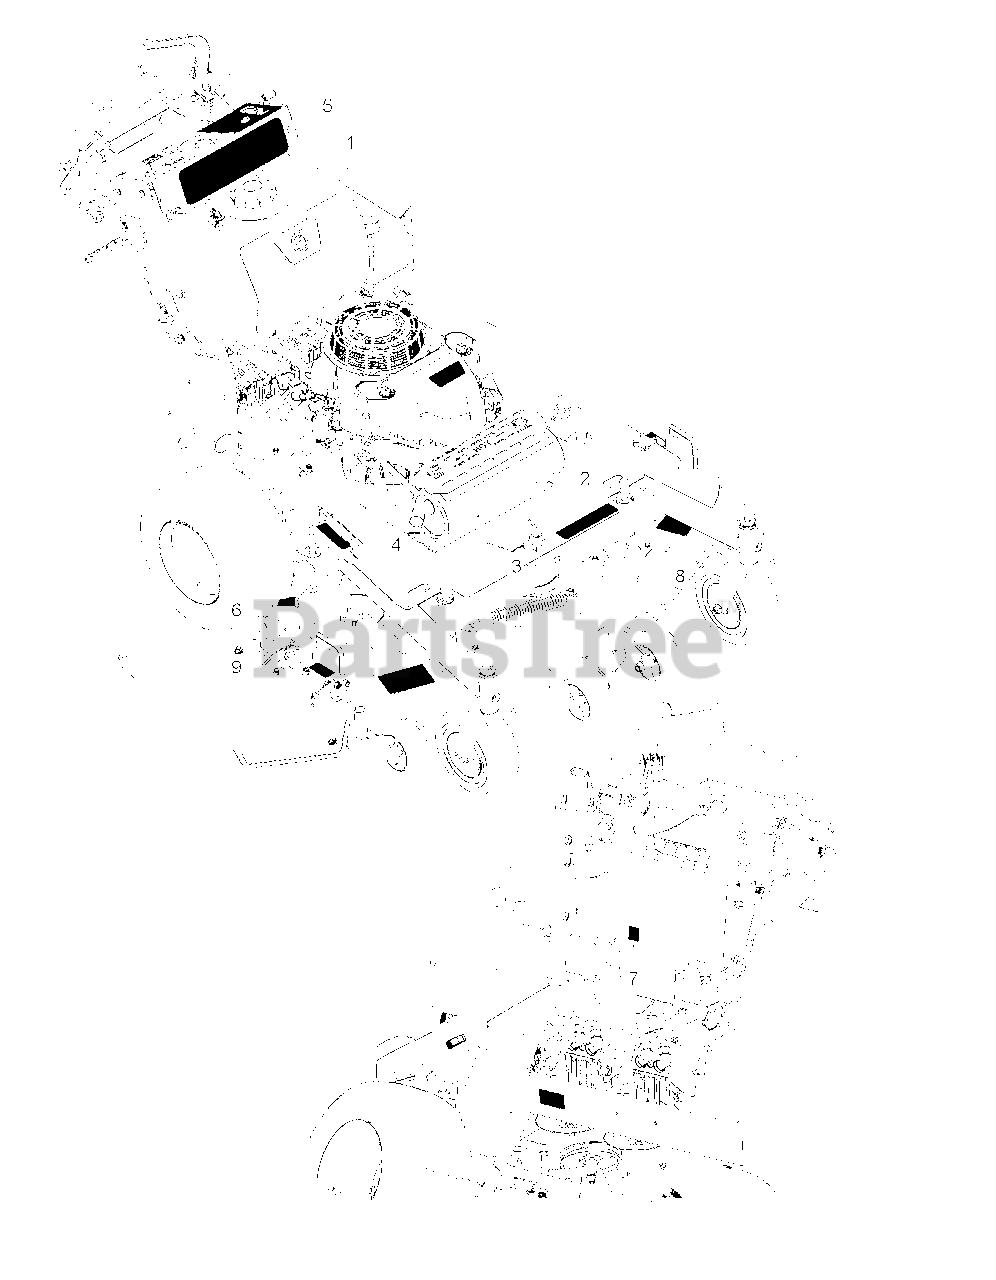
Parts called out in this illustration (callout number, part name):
5	DECAL SOURCED STAND-ON GRAPHIC
6	DECAL DECAL, SAFETY - DECK GUA
7	DECAL HOT SURFACE 7754100
8	DECAL DECAL, SAFETY - MOWER DE
9	DECAL PUMP BELT ROUTING 200469
